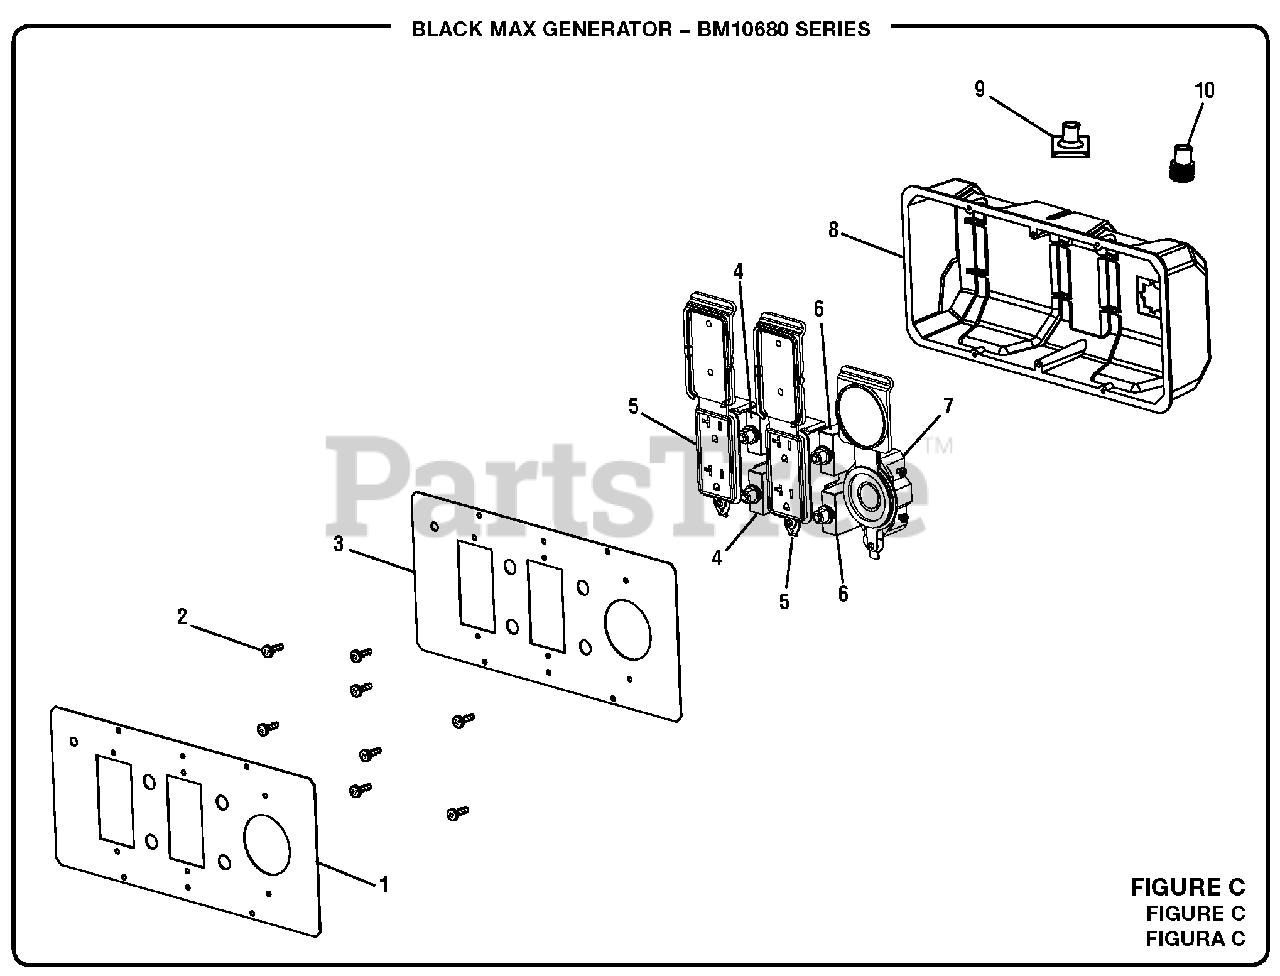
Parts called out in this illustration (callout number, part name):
1	Label (Power Outlet)
2	Screw (6-20 x 3/8 in)
3	Front Panel
4	Circuit Breaker (20 Amp, 125 Volt)
5	120 Volt Duplex Receptacle
6	Circuit Breaker (30 Amp)
7	Twist Lock Receptacle (120/240 Volt, 30 Amp, L14-30R)
8	Control Box (Back Panel)
9	Rubber Boot (Control Panel Assembly)
10	Rubber Boot
